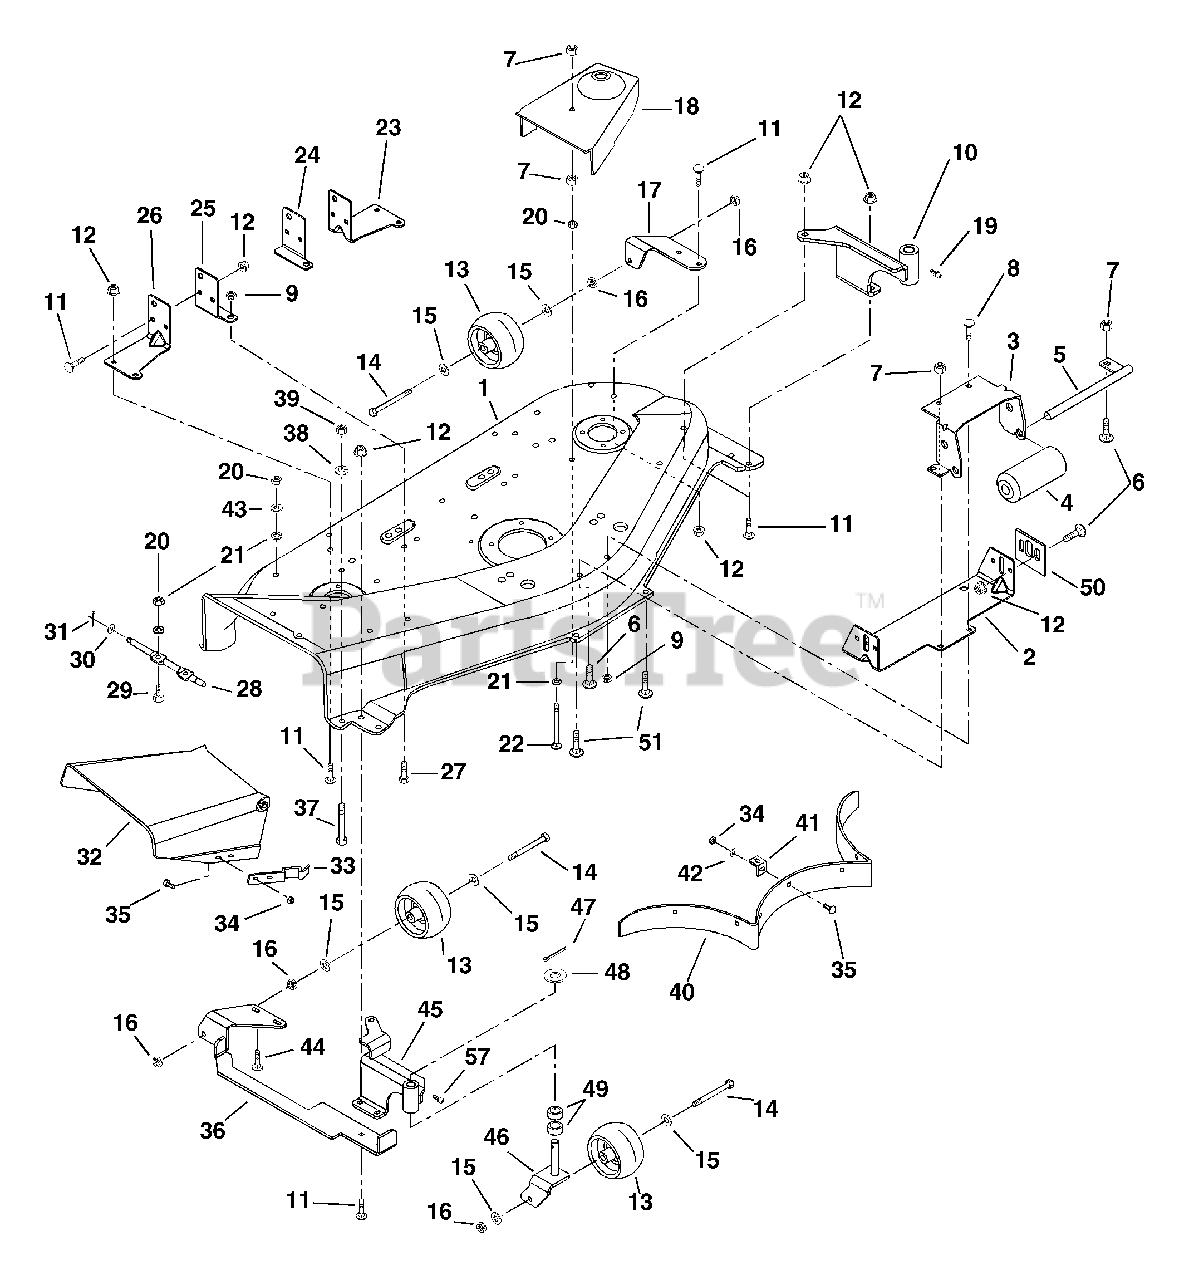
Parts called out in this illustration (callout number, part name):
1	Mower Pan Head w/Decals 48"
2	Front Hanger
3	Bracket, Roller
4	Roller
5	Roller Shaft
6	Bolt-Round Head Square Neck .31-18 x .75 Grade 5
7	Nut-Locking-Center .312-18
8	Bolt-Round Head Square Neck .50-13 x .75 - Short Neck
9	Nut-Locking-Center .50-13 Grade 5
10	Weldment-Left Front
11	Bolt-Round Head Square Neck .31-18 x .75
12	Nut-Locking-Flange .312-18
13	Roller
14	Bolt-Hex .38-16 x 3.50 Grade 5
15	Washer-Flat-Steel .38 x .875 x .083
16	Nut-Locking-Center .375-16
17	Bracket-Left Rear
18	Belt Cover Right Hand 48"
18	Belt Cover Left Hand 48"
19	Fitting-Lube .25-20 x .256
20	Nut-Locking .312-18
21	Washer-Lock .312 x .097
22	Bolt-Round Head Square Neck .31-18 x 3.25 - Short Neck
23	Left Hand Rear Hanger
24	Left Hand Rear Hanger Support
25	Right Hand Rear Hanger Support
26	Right Hand Rear Hanger
27	Bolt-Hex .50-13 x 1.00 Grade 5
28	Hinge Pin
29	Bolt-Hex .31 x .75 Grade 5
30	Washer-Flat-Steel .406 x .812 x .065
31	Pin-Cotter .09 x .75
32	Chute Extension
33	Flat Spring
34	Nut-Locking-Center .250-20
35	Bolt-Round Head Square Neck .25-20 x .50
36	Weldment-Right Rear
37	Bolt-Hex .38-16 x 2.50 Grade 5
38	Washer-Lock .375 x .155
39	Nut-Hex .375-16
40	Baffle
41	Baffle Tab
42	Washer-Flat-Steel .281 x .620 x .065
43	Washer-Flat-Steel .312 x .734 x .065
44	Bolt-Round Head Square Neck .312-18 x 1.00 Grade 5
45	Weldment-Right Front
46	Caster Fork Weldment
47	Pin-Cotter .18 x 1.25
48	Washer-Flat-Steel .630 x 1.005 x .062
49	Bushing-Sleeve .625 x .750 x .500
50	Mower Adjustment Tab
51	Bolt-Round Head Square Neck .31-18 x 1.50 Grade 5
